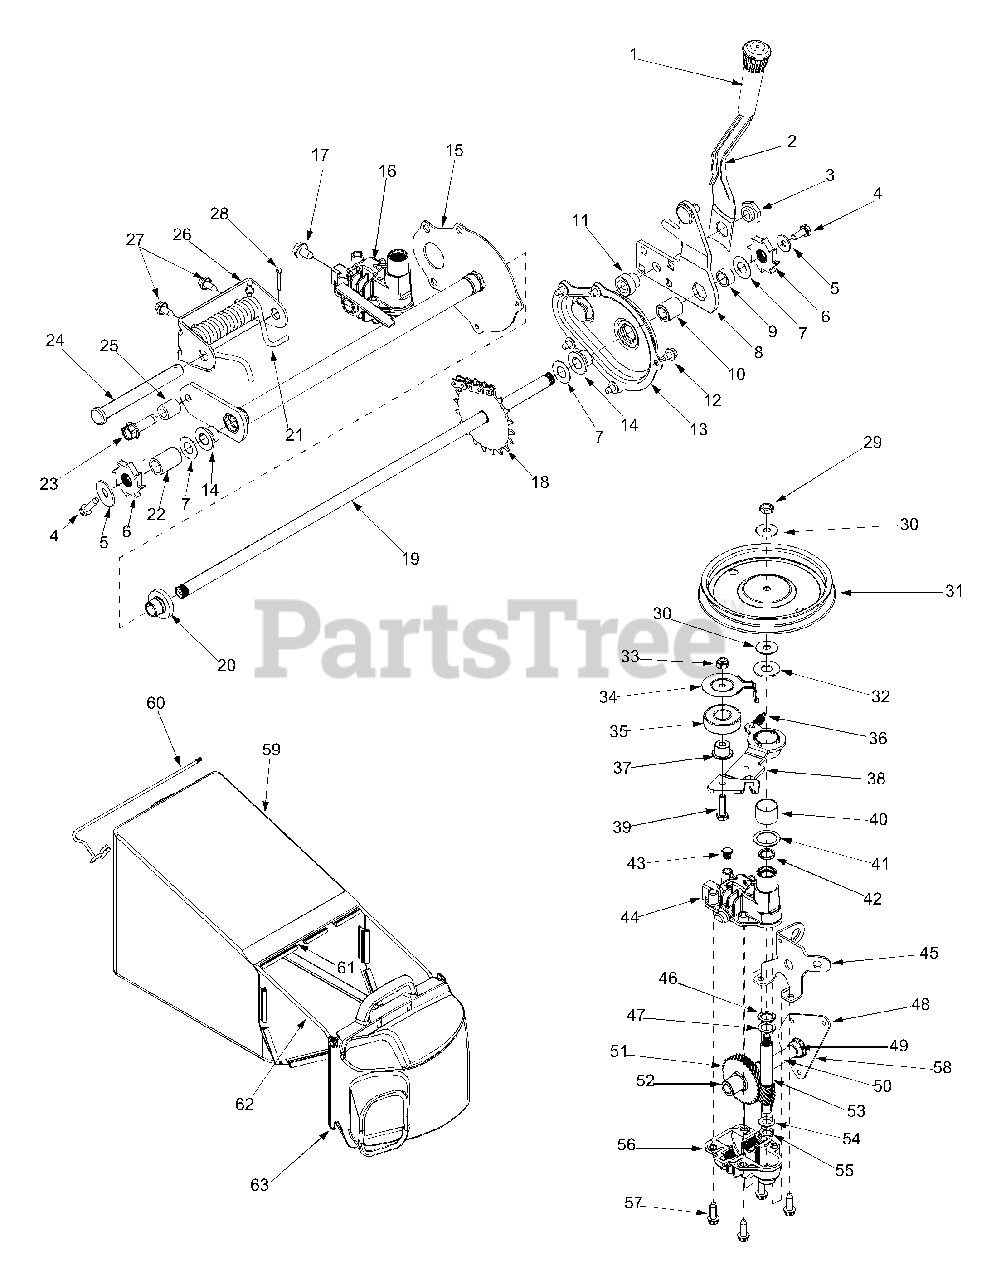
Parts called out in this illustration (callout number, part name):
2	Spring Lever
3	Shoulder Nut .825 x .165 Lg.
4	Cap Screw 1/4-20 x .620
5	Bell Washer .285 ID x .75 OD
6	Wheel Rachet
7	Flat Washer .508 ID x 1.0 OD
9	Spacer .510 ID x .70 OD
10	Sleeve Bearing .504 ID x .830 OD
11	Shoulder
12	Tap Screw 1/4-20 x .375
16	Transmission Assembly Complete
17	Hex Screw 5/16-18
18	Chain
19	Rear Axle Assembly
20	Flange Bearing .506 ID x .715 Lg
21	Torsion Spring
22	Spacer .550 ID x .750 OD
23	Screw 3/8-16 x .25
24	Clevis Pin .50 Dia x 4.82 Lg.
25	Spacer .385 ID x .624 OD
28	Cotter Pin
29	Hex Jam Nut 5/16-24
30	Bell Washer .325 ID x .930 OD
32	Flat Washer .510 ID x 1.120 OD
33	Hex Jam Nut 1/4-28
34	Belt Keeper
35	Bearing
36	Extension Spring
37	Flange Spacer
38	Idler Bracket Assembly
39	Hex Cap Screw 1/4-28 x 1.0
40	Bearing Sleeve
41	Flat Washer .885 ID x 1.45 OD
42	Oil Seal
44	Upper Housing Assembly
47	Thrust Washer .504 ID x .70 OD
48	Pivot Bracket
49	Flange Bearing
50	Output Shaft 6T
52	Bearing
53	Pinion Shaft 10T
54	Thrust Washer 3/8 x .70
55	Thrust Washer .388 x .625
56	Lower Housing Assembly
57	Hex Screw 1/2-20 x .75
58	Shaft Assembly
59	Grassbag
61	Pivot Rod
63	Grassbag Cover
